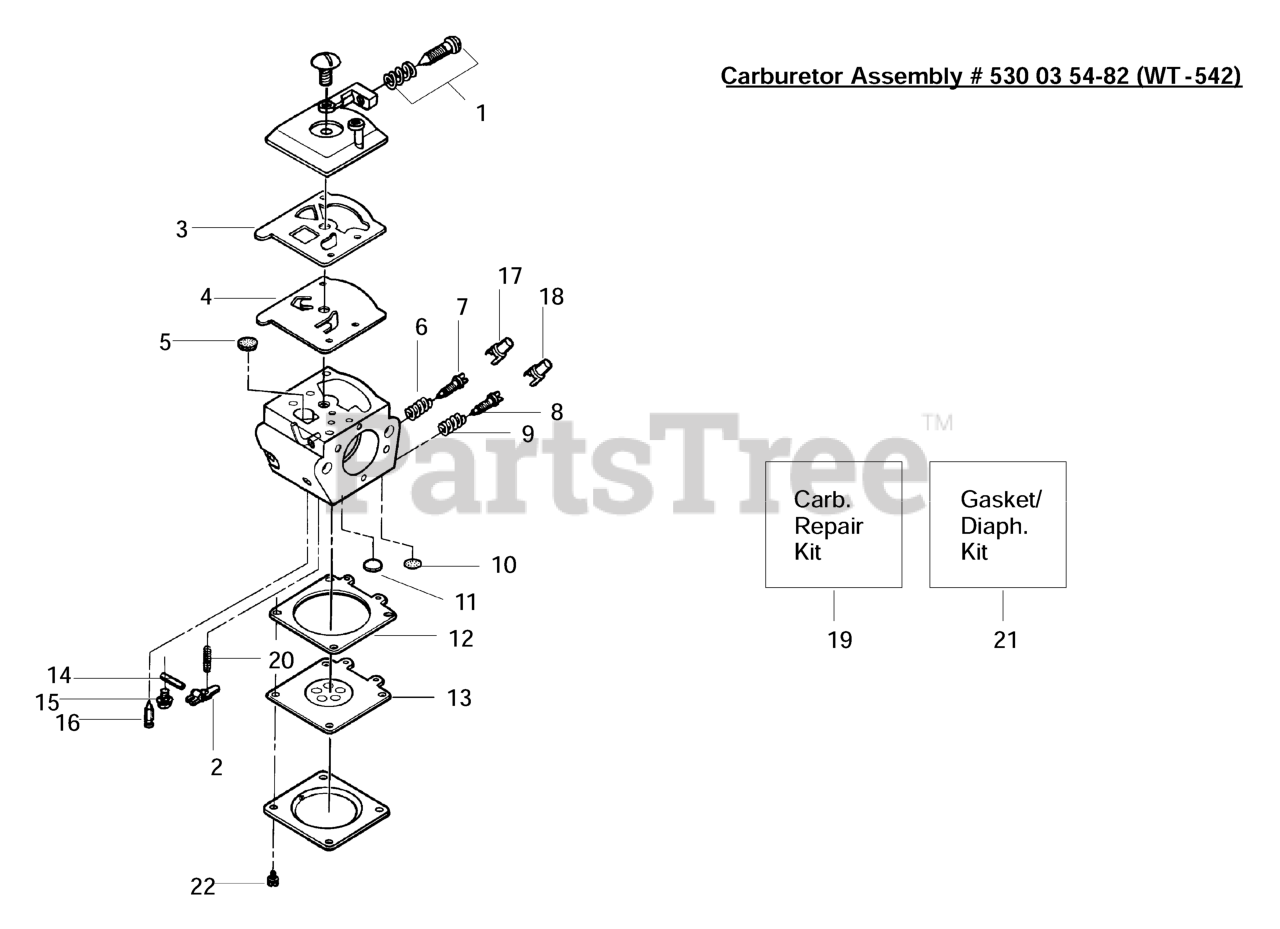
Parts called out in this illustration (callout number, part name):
1	IDLE ADV SCREW KIT
2	LEVER
3	GASKET-FUEL PUMP
4	DIAP FUEL PUMP
5	FILTER SCREEN
6	NEEDLE SPRING
7	LOW SPEED NEEDLE
8	High Speed Needle
9	NEEDLE SPRING
10	Welch Plug (5/16)
12	METERING DIA GASKET
13	DIAPHRAGM
14	PIN
16	INLET NEEDLEVALVE
17	LIMITER CAP-HIGH
18	LIMITER CAP-LOW
19	CARB REPAIR KIT
19	KIT, CARB REPAIR
20	SPRING-METERING LEVER
21	GASKET/DIAPHRAGM KIT
21	GASKET/DIAPHRAGM KIT ZAMA
22	SCREW, MOTOR COVER
530035482	CARBURETOR
